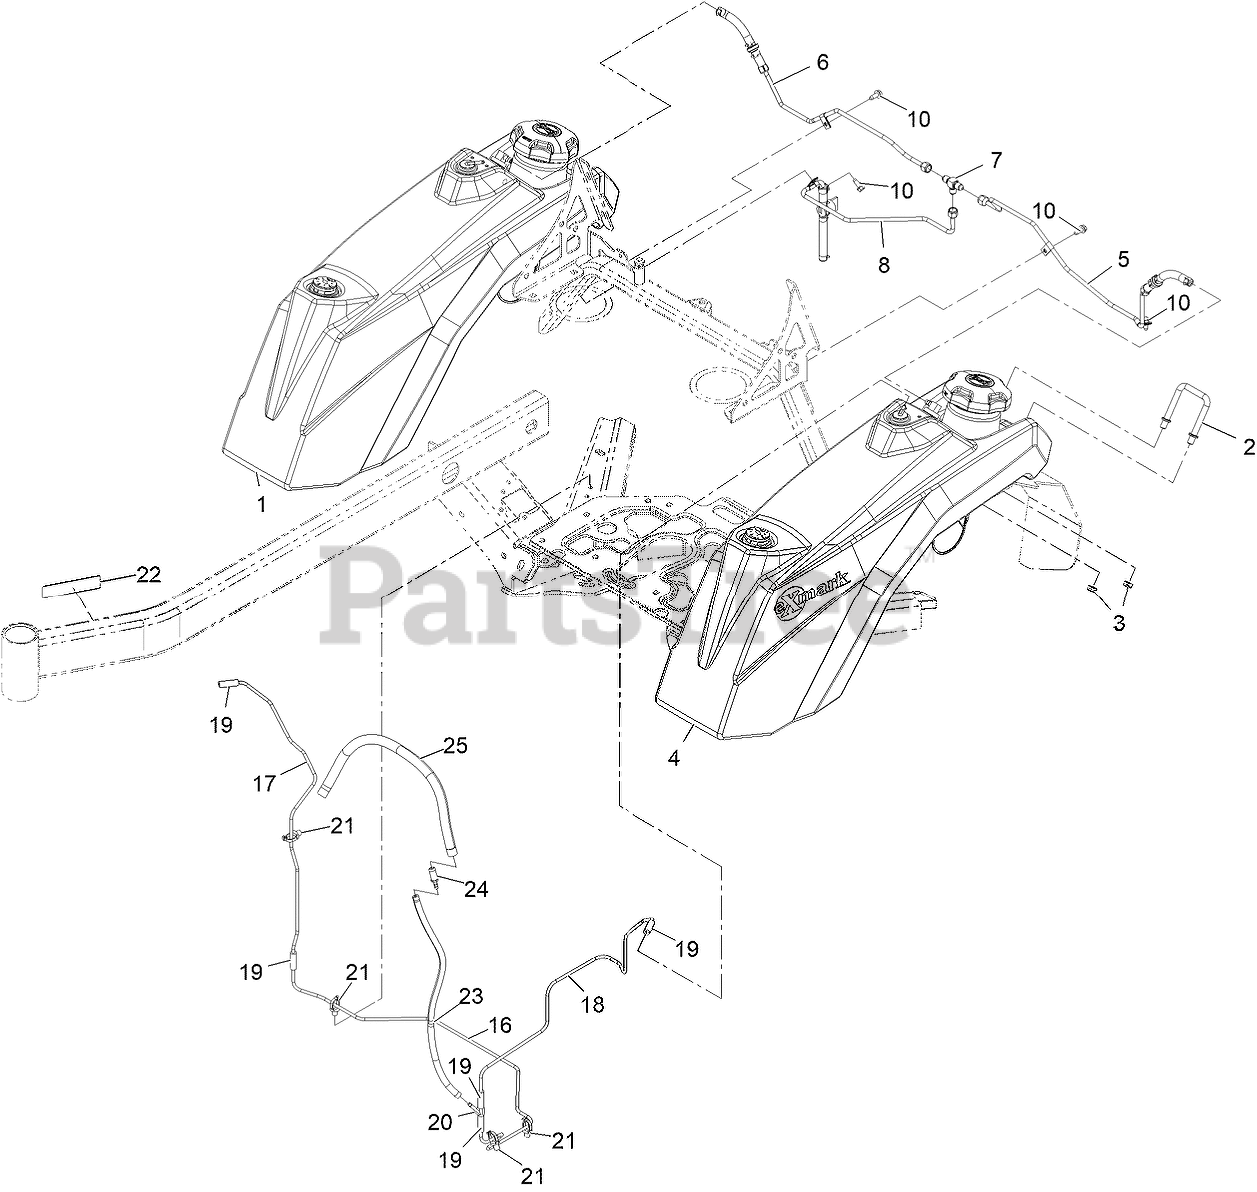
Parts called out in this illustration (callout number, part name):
1	ASM, RT FUEL TANK
2	CLAMP, TANK
4	ASM, LT FUEL TANK
5	ASM, LEFT FUEL LINE
6	ASM, RIGHT FUEL LINE
7	FITTING, 2603-4-4-4
8	ASM, KAW FUEL LINE
10	SCREW-HWH
16	LINE, VENT, MAIN
17	LINE, VENT, RIGHT
18	LINE, VENT, LEFT
19	HOSE-FUEL
20	FITTING, 3/16" Y
21	CLIP-TIE
22	DECAL-ARRESTOR, SPARK
23	HOSE, VENT
24	FITTING-STRAIGHT
25	HOSE-FUEL
